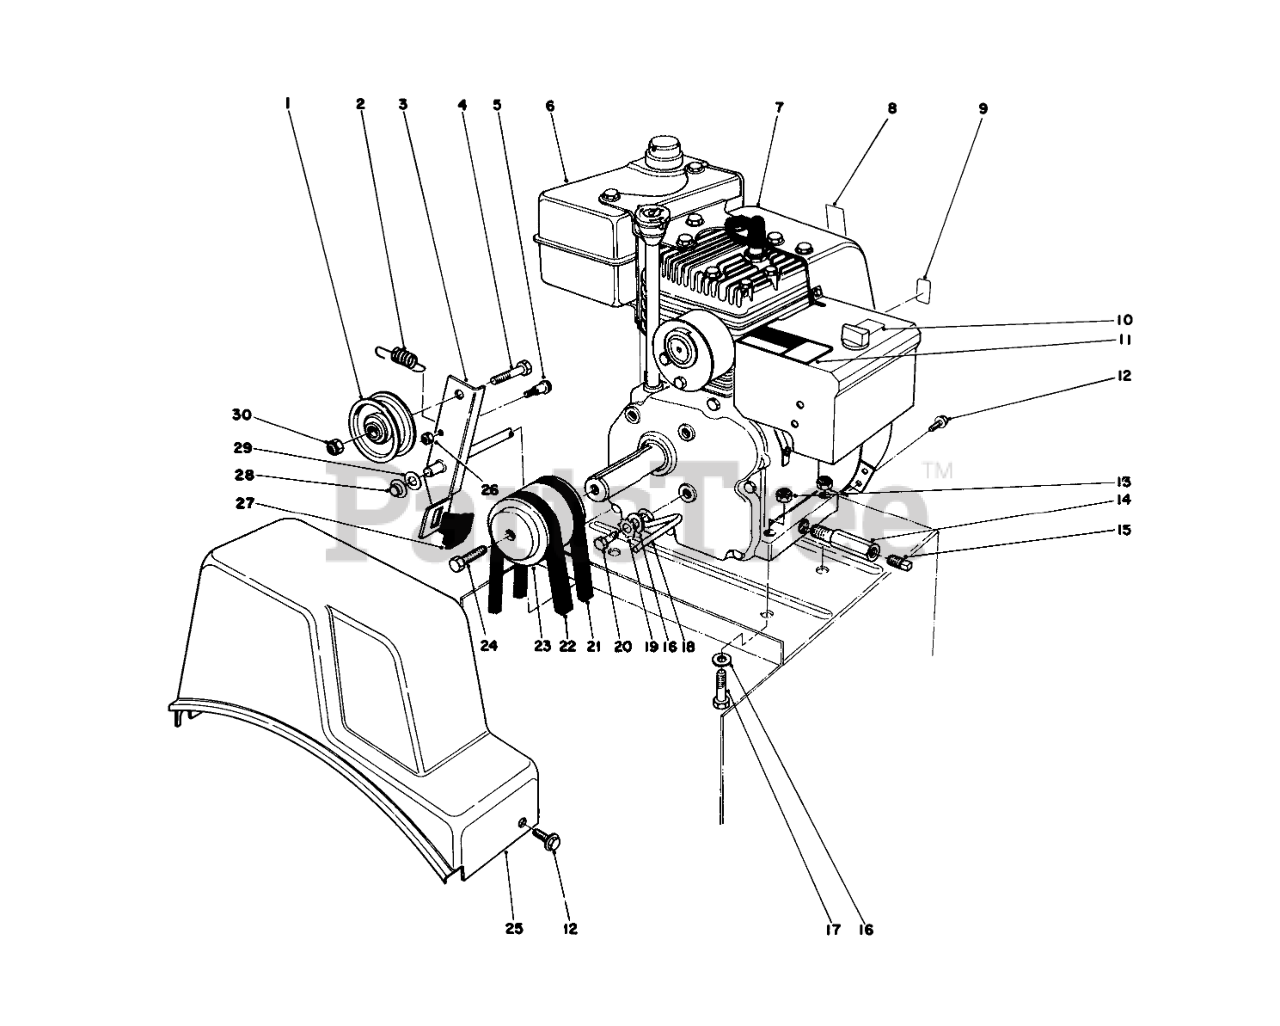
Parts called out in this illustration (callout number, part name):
1	PULLEY-IDLER
2	SPRING
3	Auger Clutch Rod Assembly (Incl. Ref. #27)
4	SCREW-HH
5	BOLT-SHOULDER
6	GAS TANK 2 QT W CAP
7	Engine
8	PRIMER DECAL
9	DECAL THROTTLE
10	CHOKE DECAL
11	HOT SURFACE DECAL
12	SCREW-HWH
13	NUT-LOCK, NI
14	PIPE-NIPPLE
15	CAP-PIPE
16	WASHER-PLAIN
17	SCREW-HH
18	RETAINER-BELT
19	WASHER-LOCK
20	SCREW-HH
21	V BELT-3L, TRACTION
22	V-BELT (29.50 INCH)
23	PULLEY-ENGINE
24	SCREW-SPECIAL
25	COVER-BELT
26	NUT-LOCK, CONE
27	Brake Pad
28	RETAINER-PUSH ON
29	WASHER-FLAT
30	NUT-LOCK, CONE
